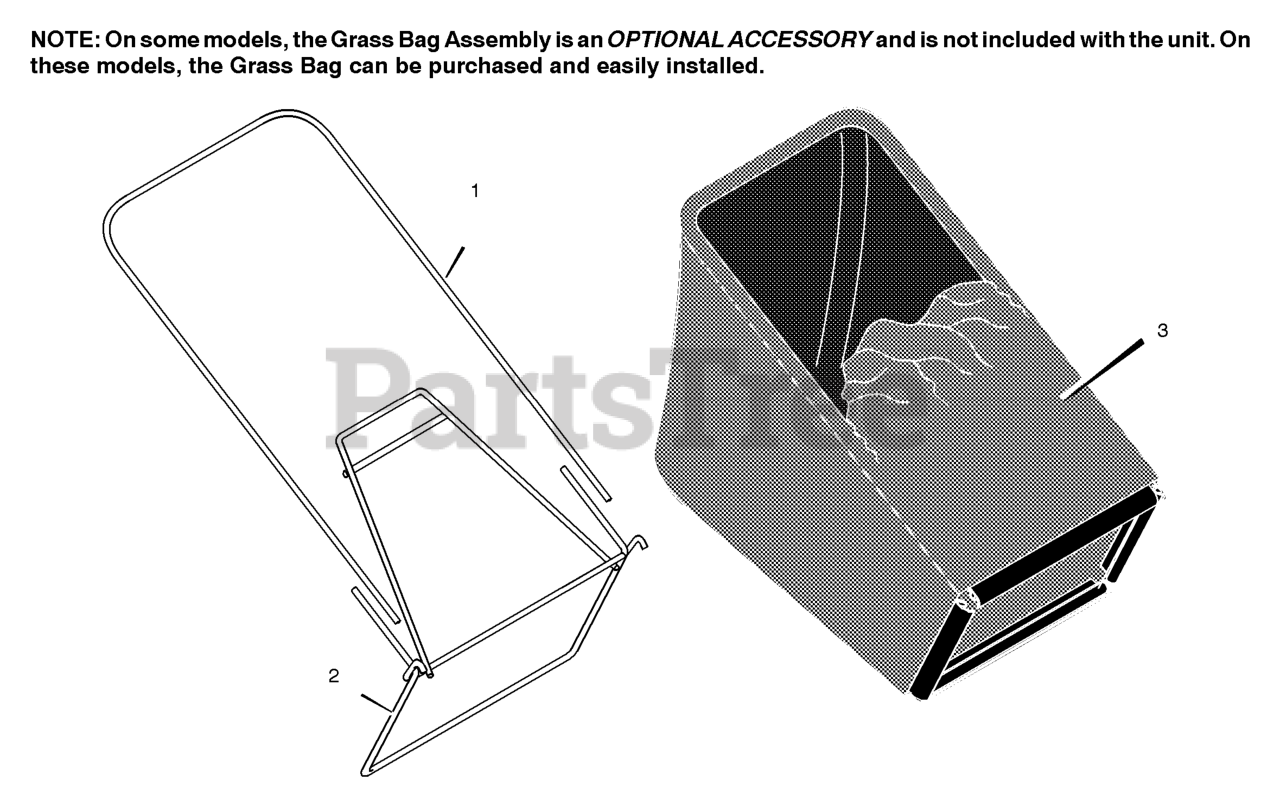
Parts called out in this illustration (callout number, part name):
1	Frame, Top
1-3	Bagger Assembly, Complete
2	Frame Assembly
3	Bag, Cloth - Black
